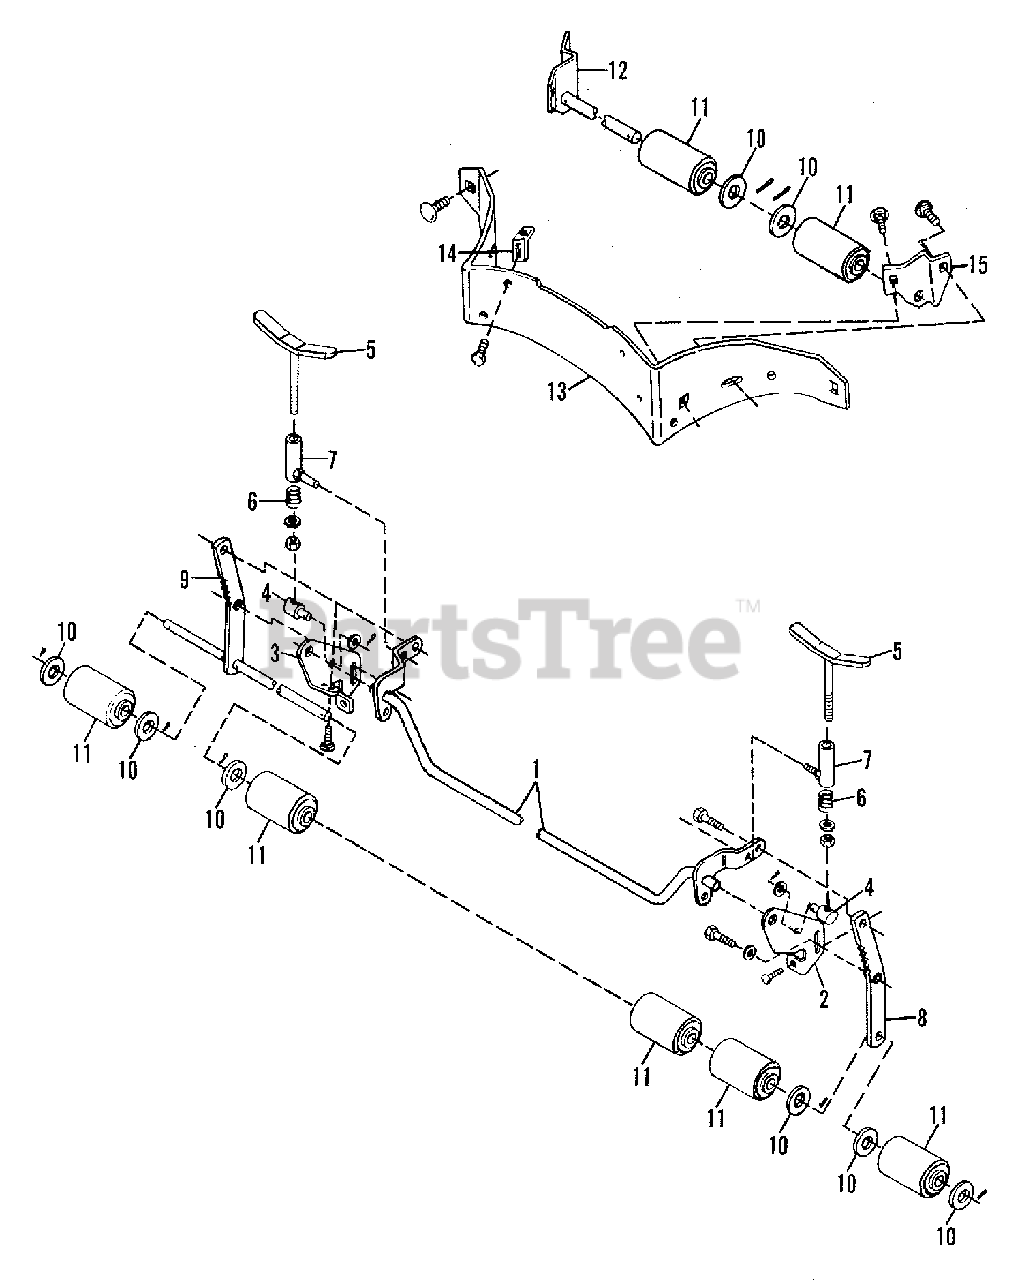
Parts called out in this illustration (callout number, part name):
1	ARM ASSEMBLY, Roller
1	CAPSCREW, 3/8NC x 1
2	BRACKET, Roller, L.H.
2	CAPSCREW, 3/8NC x 1
2	BOLT, Carriage, 3/8NC x 3/4
2	WASHER, Plain, 7/16 x 1 x 14 GA.
2	LOCKWASHER, 3/8
3	BRACKET, Roller, R.H.
3	CAPSCREW, 3/8NC x 1
3	BOLT, Carriage, 3/8NC x 3/4
3	WASHER, Plain, 7/16 x 1 x 14 GA.
3	LOCKWASHER, 3/8
4	WASHER, Plain, 13/32 x 7/8 x 14 Ga
4	PIN, Cotter, 3/32 x 1"
5	SCREW, Adjusting
5	WASHER, Plain, 7/16 x 1 x 14 GA.
5	NUT, Jam, 3/8NC
7	SOCKET ASSEMBLY
7	NUT, Lock, 3/8NC
8	BAR, Roller
9	SHAFT ASSEMBLY, Roller
9	WASHER, Plain, 41/64 x 1-1/4 x 14 Ga.
9	PIN, Cotter, 3/16 x 1
12	BRACKET & SHAFT ASSEMBLY
12	WASHER, Plain, 41/64 x 1-1/4 x 14 Ga.
12	PIN, Cotter, 3/16 x 1
13	BOLT, Carriage, 3/8NC x 3/4
13	LOCKWASHER, 3/8
13	CAPSCREW, 1/4NC x 5/8
13	LOCKWASHER, 1/4
14	CLIP, Baffle
14	SCREW, Thread Forming, 1/4NC x 3/4
14	CAPSCREW, 1/4NC x 5/8
14	WASHER, Plain, 5/16 x 3/4 x 16 Ga.
14	LOCKWASHER, 1/4
15	BRACKET, Roller, L.H.
15	BOLT, Carriage, 5/16NC x 3/4
15	LOCKWASHER, 5/16
15	NUT, 5/16NC
